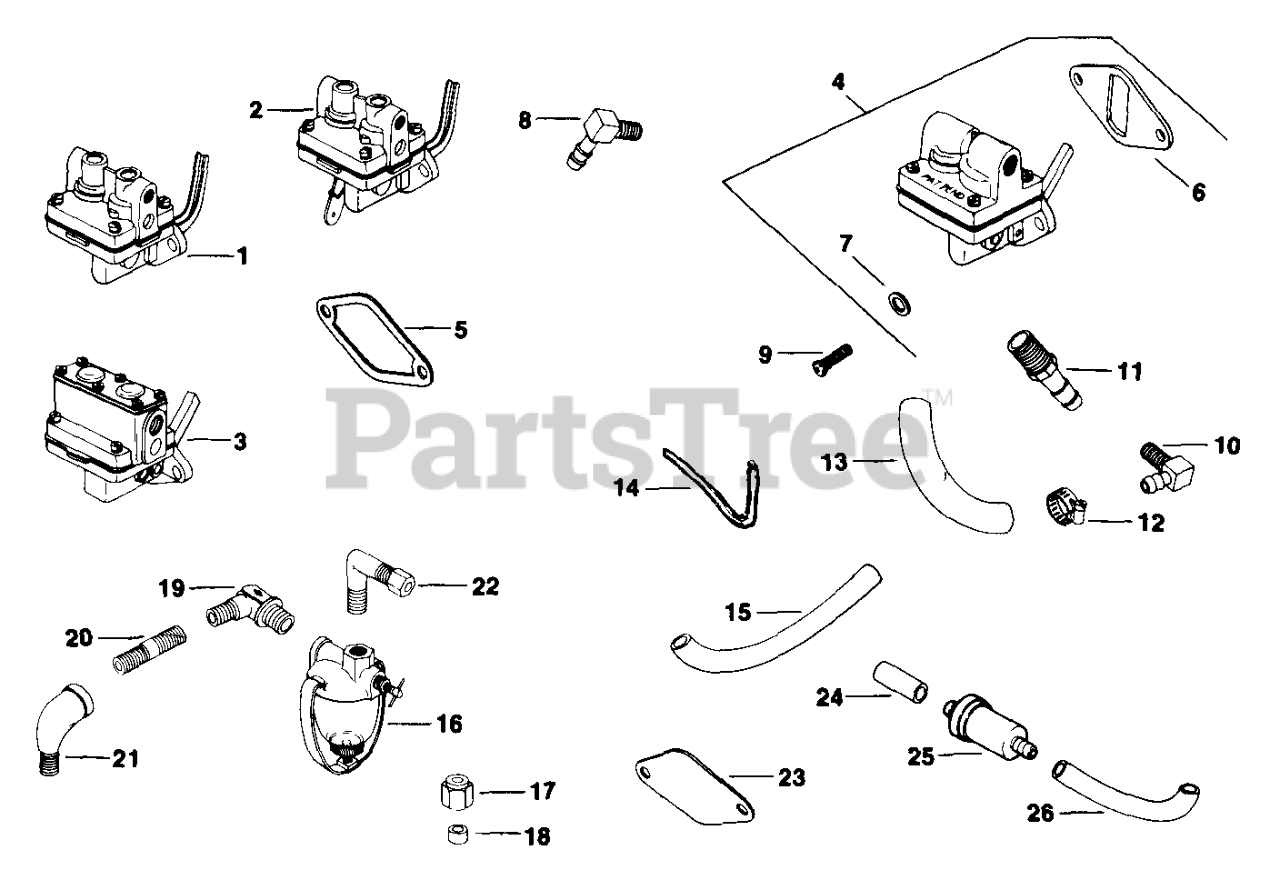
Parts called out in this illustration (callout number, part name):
2	KIT, FUEL PUMP USE 47 559 11-S
6	GASKET - USE 25 041 05
9	SCREW, SEMS 1/4-20X3/4"
13	LINE - USE 25 353 01
23	PLATE, FUEL PUMP COVER
